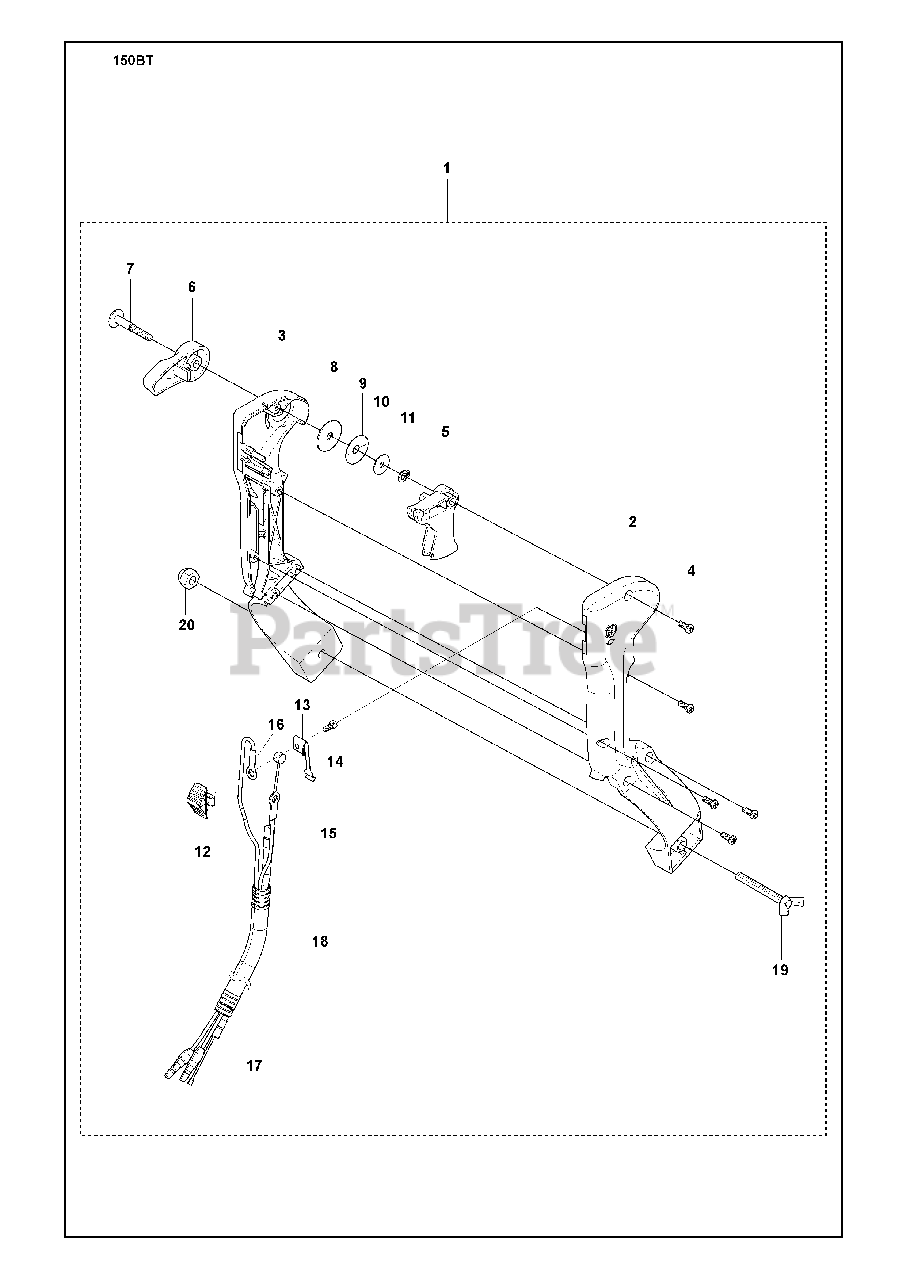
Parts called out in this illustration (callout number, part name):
4	SCREW 4X14(T)
5	LEVER THROTTLE
6	RP_LEVER (RPLS T402325430)
7	SHAFT
8	WASHER(T)
9	RP_SPRING WASHER
11	RP_CLIP(T)
12	SWTICH (T)
13	SPRING (RPLS T402325720)
14	RP_SCREW 4X10(T)
18	TUBE (RPLS T402383210)
